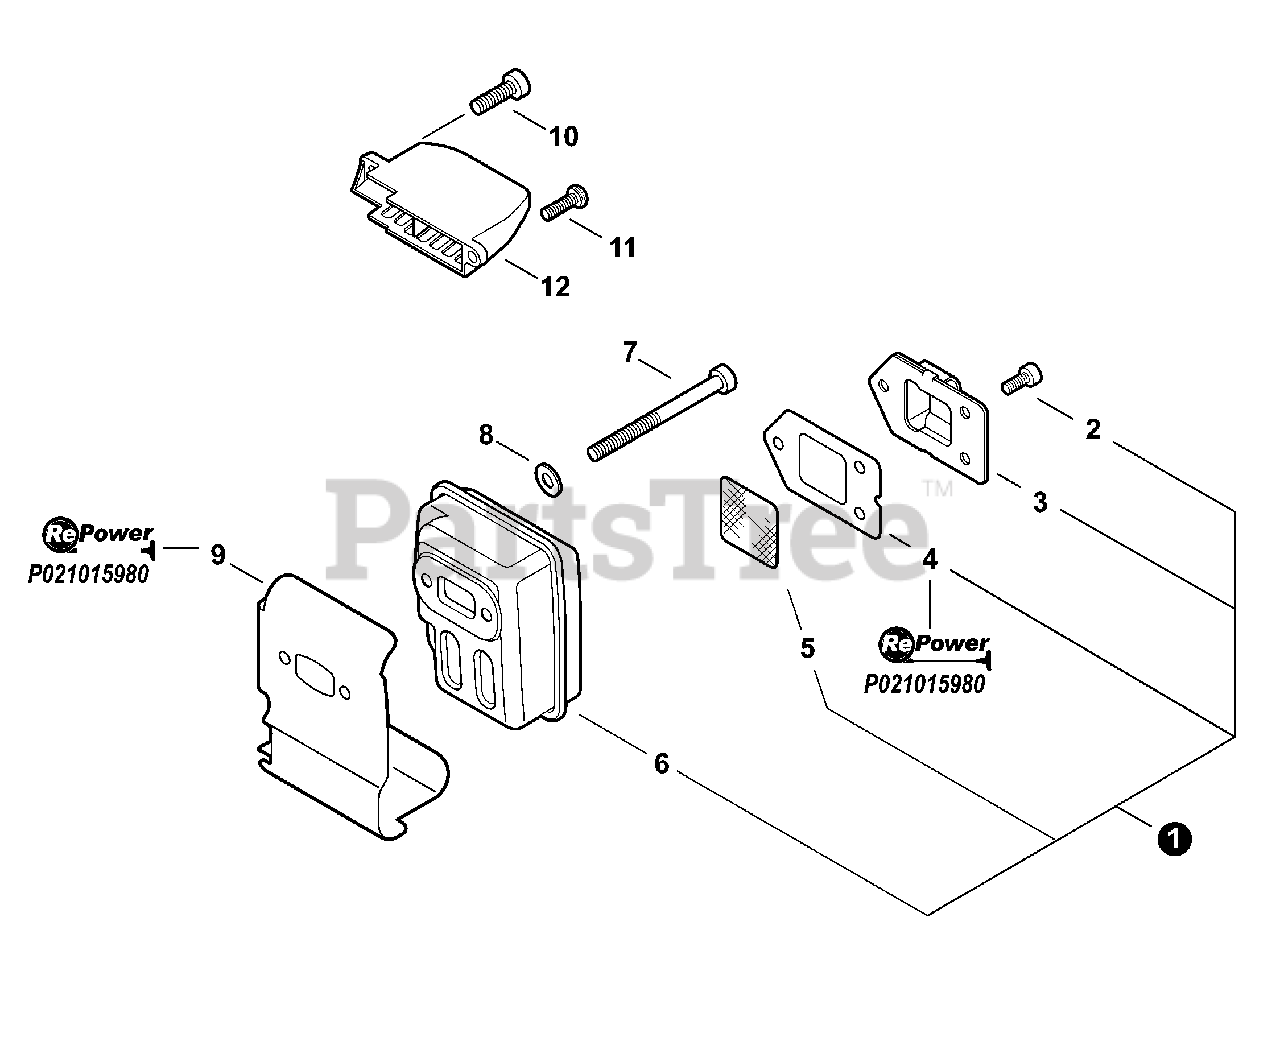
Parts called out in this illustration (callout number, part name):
1	MUFFLER ASSY
2	BOLT, TORX 4×8
3	GUIDE, EXHAUST
4	GASKET, EXHAUST
5	SCREEN, SPARK ARRESTER
7	BOLT, TORX 5×55
8	WASHER, FLAT 5.5×10×0.8
9	HEAT SHIELD, EXHAUST
10	BOLT, TORX 5×16
11	BOLT, TORX 5×16
12	COVER, MUFFLER
